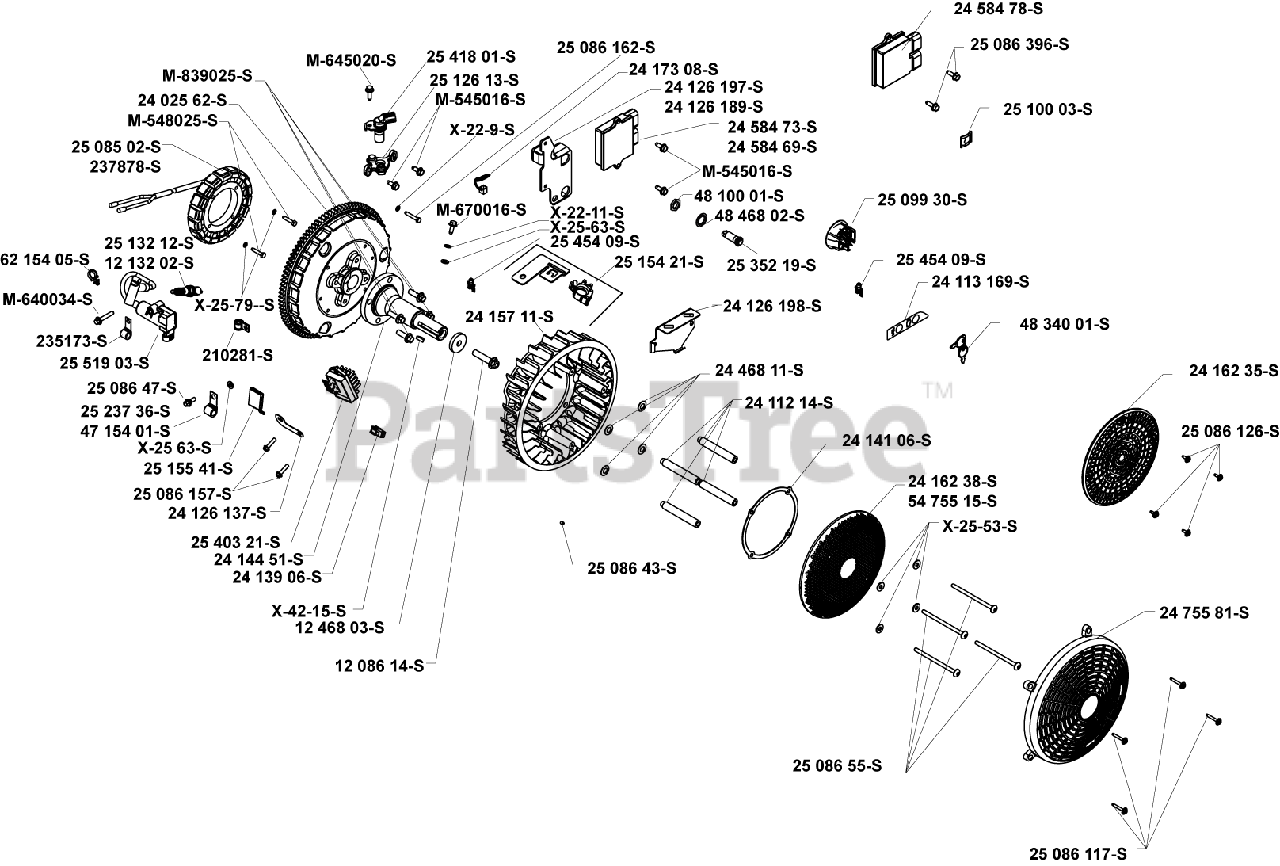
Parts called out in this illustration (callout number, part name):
1	KIT, 15 / 20 AMP STATOR
2	SCREW, THREAD FORMING
3	FLYWHEEL ASSEMBLY
5	SCREW, THREAD FORMING
6	SENSOR, SPEED
7	BRACKET, SENSOR SPEED
8	SCREW, THREAD FORMING
9	WASHER, INT TOOTH LOCK #10
10	CAP, CONNECTOR
11	BRACKET, ECU
12	MODULE, ECU
26	WASHER, FLAT 1/4" (O.D. 5/8")
28	SCREW, CAP M6X1.0X99.5
29	SCREEN, GRASS
30	SCREW, FLG M10X1.5X45 - (#25086361S)
31	RING, SUPPORT
33	WASHER, SPRING 10 MM
35	KIT, MOUNTING CLIP
36	FAN USE 24 755 253-S
37	SCREW, THREAD FORMING
38	WASHER, INT TOOTH LOCK 1/4"
41	WASHER, FLAT 1/4" (O.D. 1/2")
42	SCREW, SKT SET #10-24X1/4"
43	WASHER, FLAT 13/32"
44	KEY, 3/16" X 5/8"
47	HARNESS, WIRING ASSEMBLY
48	SCREW, HEX FLANGE HI-LO
52	CONNECTOR
57	PLUG, SPARK (STD)
63	COIL, IGNITION - EFI
64	SCREW, FLG M6X1.0X34
70	CLIP, MOUNTING BRACKET USE 25 154 21-S
96	CLAMP, INSULATED DOUBLE
97	REGULATOR, RECTIFIER (20-30AMP,FW W/O USE 25 403 39-S
